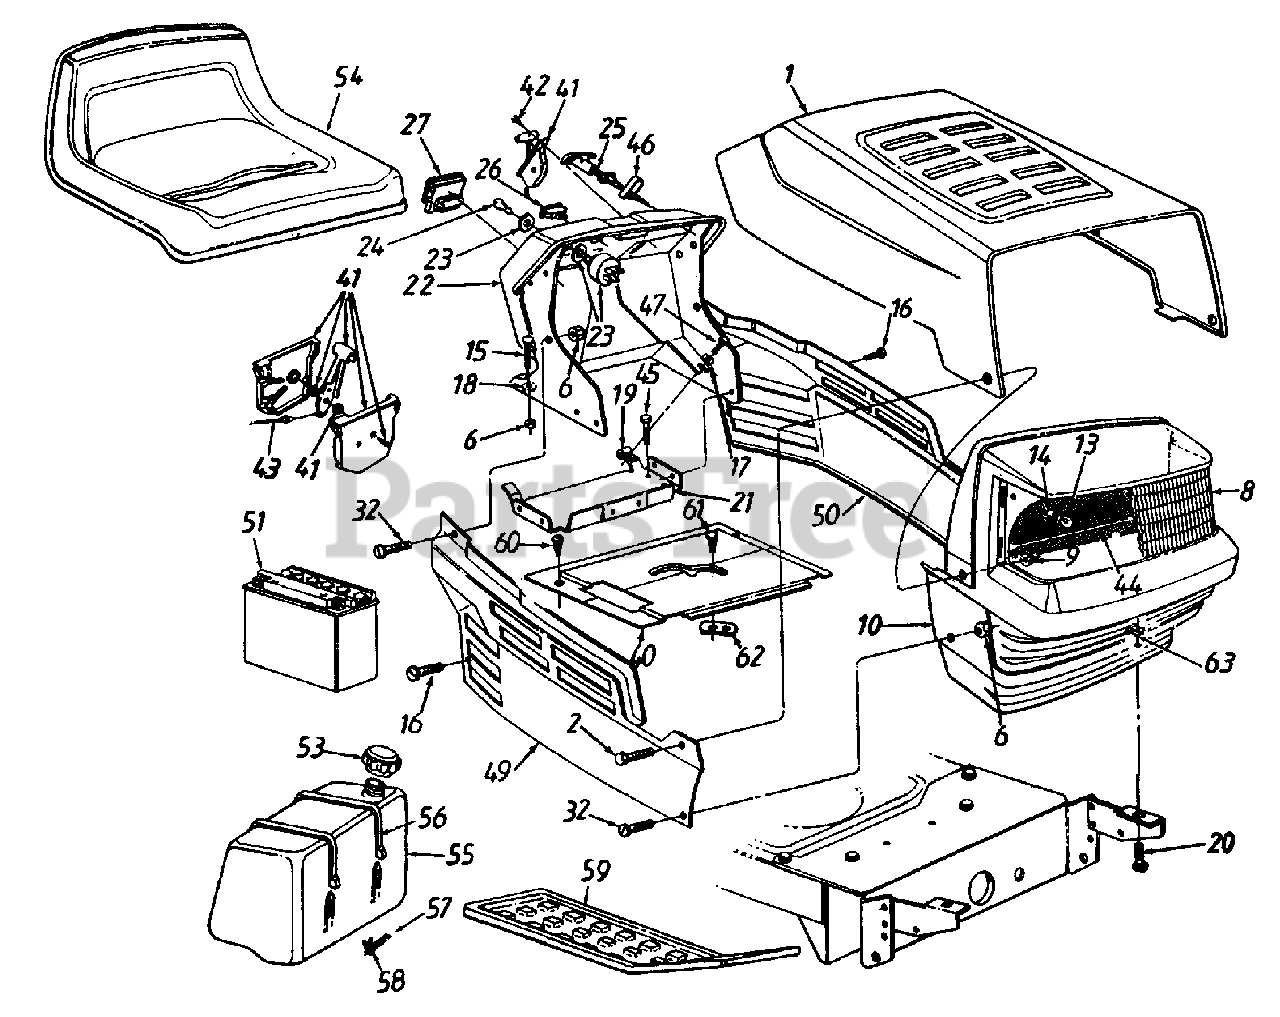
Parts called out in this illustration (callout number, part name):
6	Hex Sems Nut 1/4-20 Thd.
8	Headlight Lens
9	Flange L-Nut 1/4-20 Thd.
10	Grille
13	Lamp
14	Socket
15	Carriage Bolt 1/4-20 x . 75" Lg.
16	Hex TT-Tap Scr. 1/4-20 x . 5" Lg.
17	FL-Wash. .281" I.D. x . 73" O.D.
18	Bolt Retainer 1/4" I.D.
19	Speed Nut 1/4-20 Thd.
20	Hex Bolt 5/16-18 x .75" Lg.
23	Ignition Switch
24	Ignition Key
25	Choke Control
26	Light Switch
27	Ammeter
32	Pan Hd. Scr. 1/4-20 x .75" Lg.
42	Truss Mach. AB-Tap Scr. #10 x .5" Lg.
43	Throttle Control Wire
44	Grille Reflector Label
45	Hex B-Tap Scr. 5/16-18 x .5" Lg.
46	Choke Retainer
47	Hex TT-Tap Scr. 1/4-20 x .75"
53	Fuel Cap
54	Seat
55	Fuel Tank
56	Tie Strap
57	Fuel Line
58	Hose Clamp
59	Rubber Foot Pad-L.H.
60	Truss Mach. B-Tap Scr. #10 x .5" Lg.
61	Hex AB-Tap Scr. #8 x .5" Lg.
62	Insulator Nut Plate
63	U-Nut 5/16-18 Thd.
